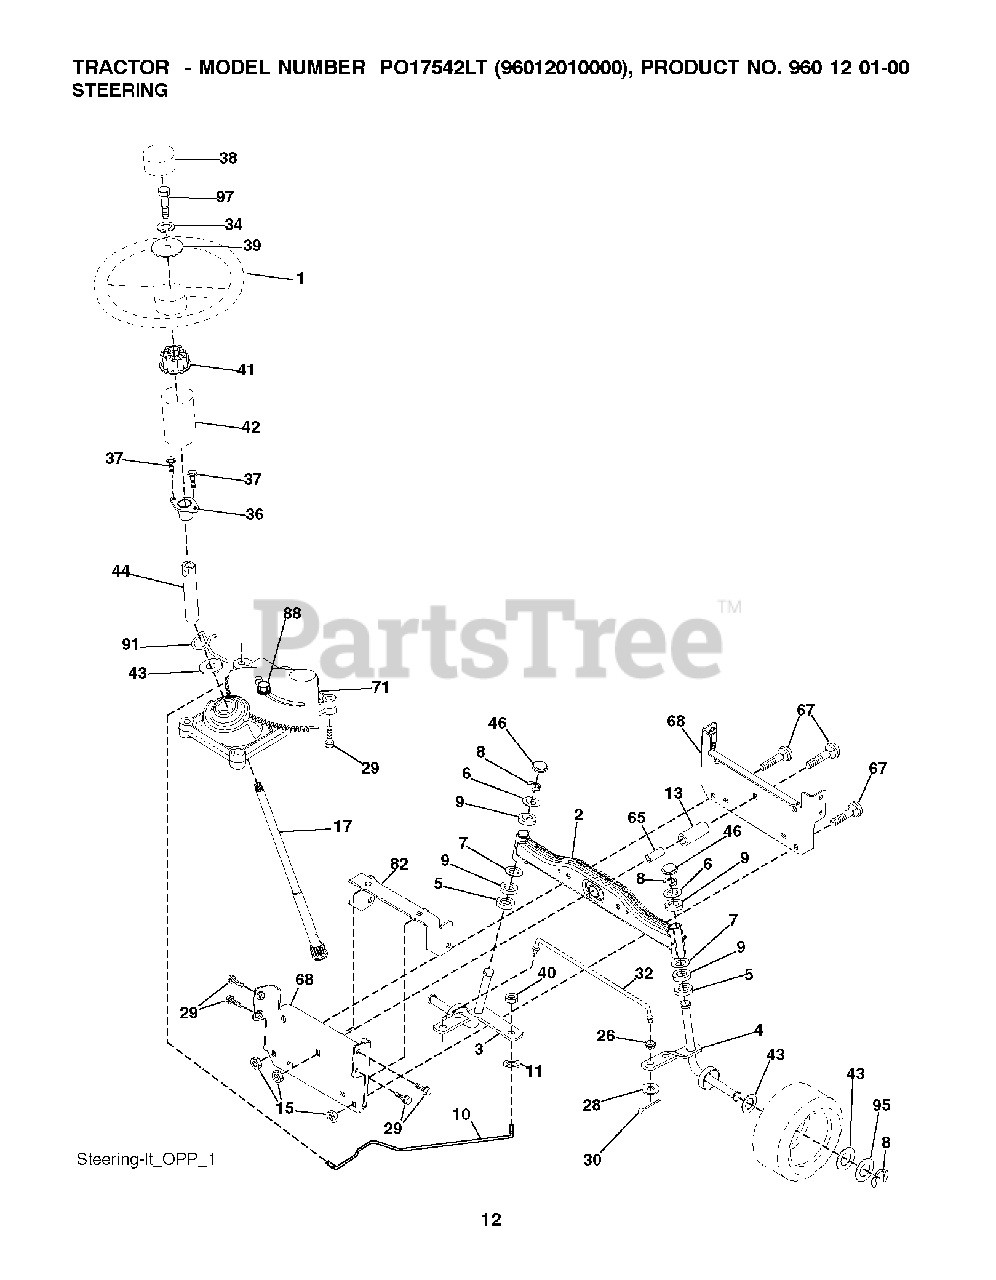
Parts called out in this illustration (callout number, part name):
1	WHEEL.STEERING.HARD.RIM.BLAC
2	AXLE HALF ASM-WELDED
3	SPINDLE.ASM.LH.15"TIRES
4	SPINDLE.ASM.RH.15"TIRES
8	RING CLIP
9	Steering Column Bearing
10	DRAGLINK.15".TIRES.2001
11	WASHER, LOCK 3/8
13	TUBE, PIVOT AXLE (2 2)
15	NUT LOCK FLG 3/8-16 UNC
26	BUSHING.DRAGLINK (2 2)
28	WASHER
29	SCREW, 3/8-16X3/4
30	COTTER PIN
32	ROD.TIE.WIRE.FORM
34	LOCKWASHER
37	SCREW.TT.#10-32X.5.3/8.FLANGE
38	INSERT, WHEEL STEERING
39	WASHER.11/32
40	NUT CROWNLOCK 3/8-24
41	ADAPTER, WHEEL STNG..
42	BOOT.STEERING.SHAFT.BLACK
44	SHAFT.EXTEN.STRG.SPLINE
46	CAP.SPINDLE.BLACK
65	SPACER.BRACE.AXLE
67	BOLT CARRIAGE
68	BRACE.AXLE.15"TIRES
71	STEERING ASM
82	BRACKET.SUSP.CHASSIS.FRONT.15
88	BOLT, SHOULDER 7/16-20
91	CLIP.STEERING
95	WASHER.HARDENED
97	BOLT 5/16-18 X 4 W/PATCH
